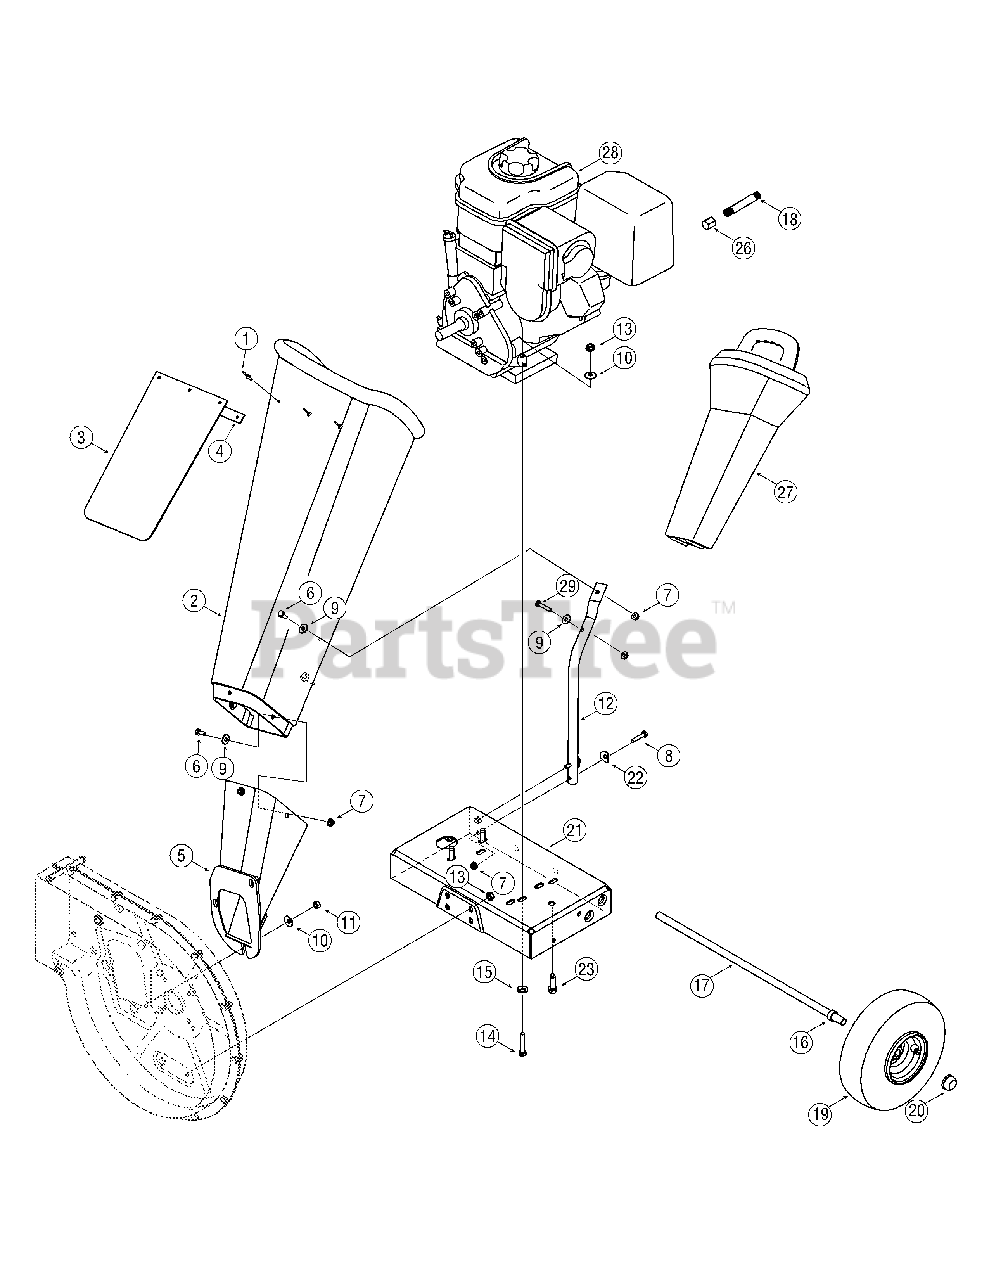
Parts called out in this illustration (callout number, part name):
1	Pop Rivet
2	Chipper Shredder Chute
3	Chute Flap
4	Chute Flap Strip
5	Chipper Chute Assembly
6	Hex Cap Screw 1/4 -20 x.620
7	Hex Lock Nut 1/4-20
8	Hex Cap Screw 1/4-20 x 1.25
9	Flat Washer .28 ID x .74 OD
10	Bell Washer .340 ID x .872 OD
11	Hex Nut 5/16-18
12	Support Brace
13	Hex Lock Nut 5/16-18
14	Hex Cap Screw 5/16-18 x 1.75
15	Bell Washer 5/16 x 1.0
16	Spacer
17	Axle Assembly
18	Pipe, Oil Drain
19	Wheel Complete, 10.0 x 4.0 Gray
20	Push Cap
22	Washer,.320 ID x.93 OD
23	Screw, 3/8-16 x 1.250
26	Oil Drain End Cap
27	Tamper
28	Replacement Engine 20T212-0835-F1
29	Hex Screw, 1/4-20 x 1.25
